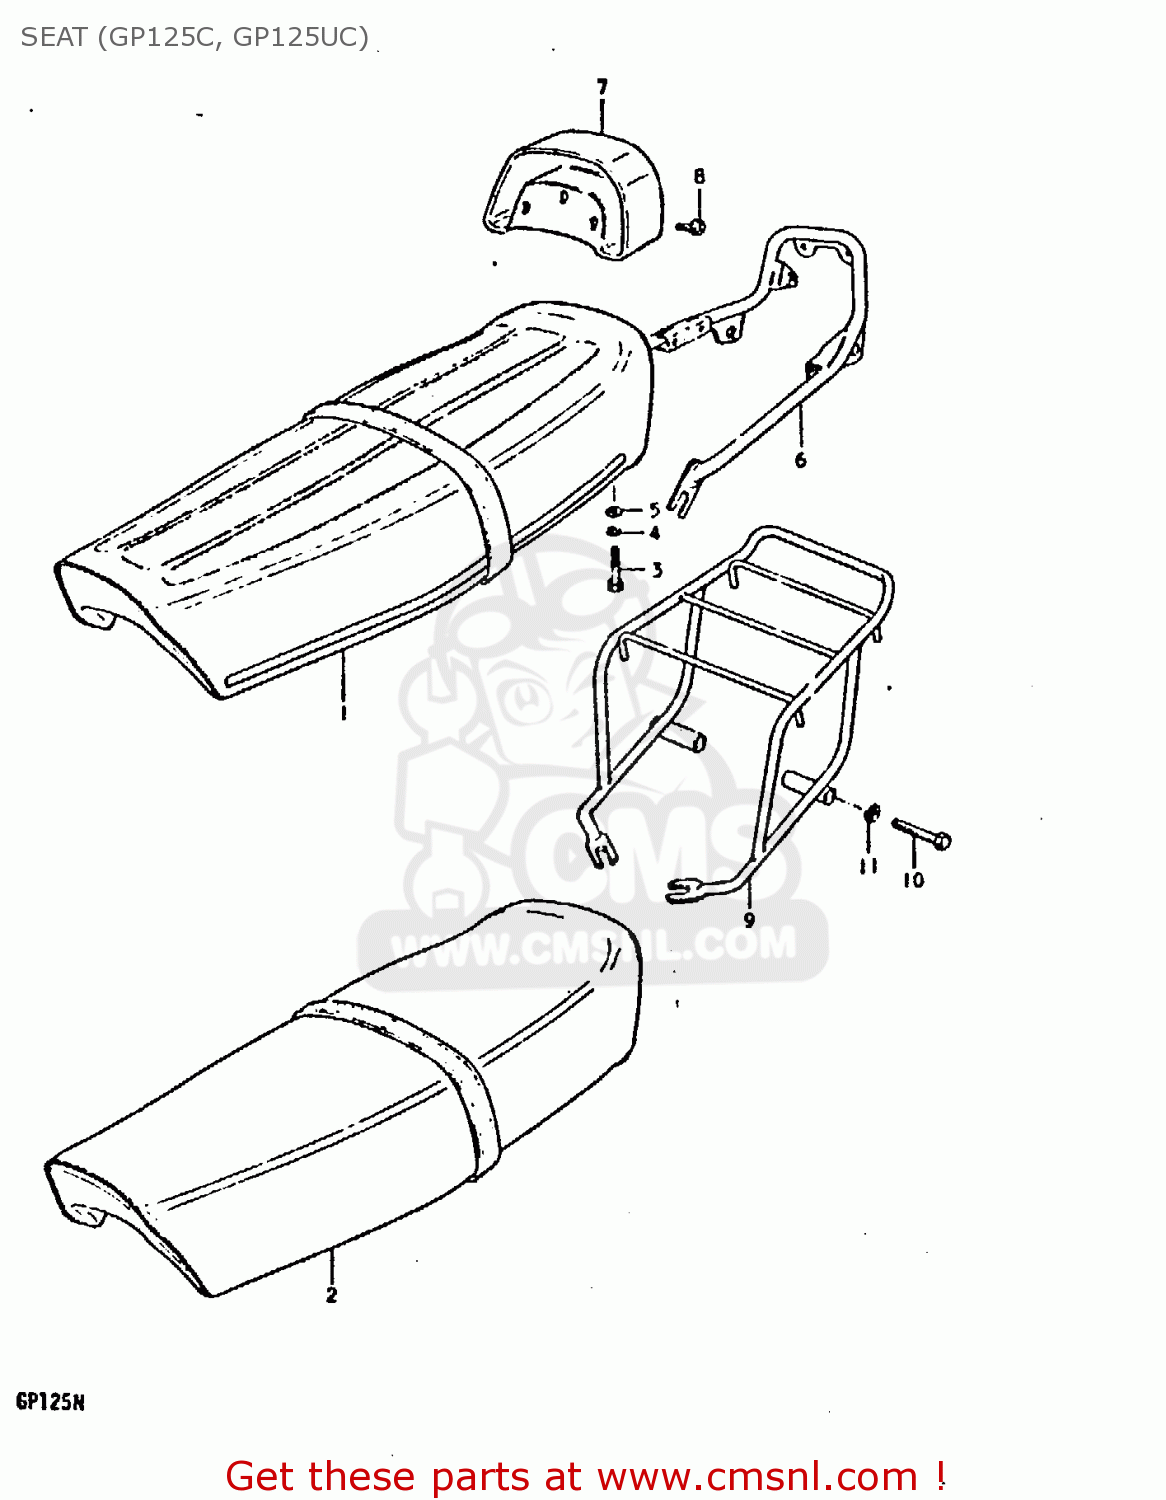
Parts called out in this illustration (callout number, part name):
2	SEAT ASSY
3	BOLT 8X40
4	LOCK WASHER
5	WASHER
6	BAR, REAR COMBINATION LAMP
9	CARRIER, SPORTS
10	BOLT
11	LOCK WASHER
